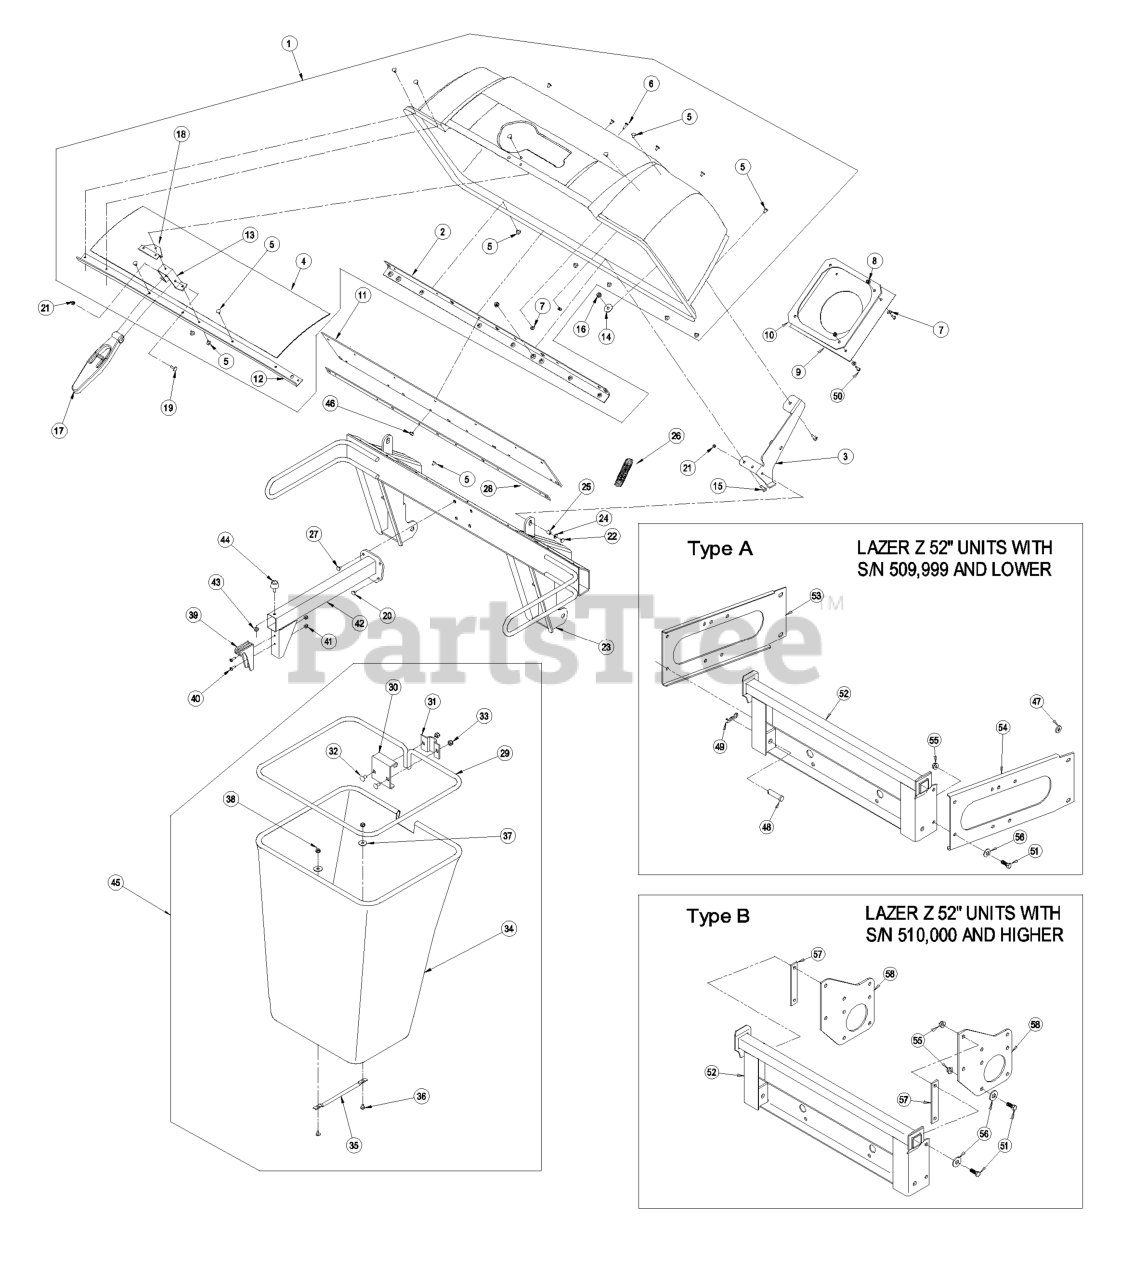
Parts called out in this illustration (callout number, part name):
1	ASM, HOOD
2	STIFFENER-BAGGER, TOP
4	SCREEN-BAGGER
5	RIVET-BLIND
6	SCREW-HEAD, TRUSS
7	WASHER-FLAT
8	NUT-LOCK, NI
9	SEAL-CHUTE
10	CLAMP-SEAL
11	SEAL-HOOD
12	SUPPORT-SCREEN
13	ANCHOR-LATCH
15	SCREW-HH
18	REINFORCEMENT-LATCH
19	SCREW-HH
20	SCREW-HSBH
21	NUT-LOCK, NI
22	SCREW-HH
23	UPRIGHT-BAGGER
24	WASHER-FLAT
26	SPRING-EXTENSION
27	SCREW-HH
28	PLATE-BACKING
29	FRAME-BAG
30	HANGER-BAG
32	BOLT-CARR
33	NUT-LOCK, NI
35	HANDLE-BAG
36	BOLT-CARR
38	NUT-LOCK, NI
40	SCREW-PPH
42	SUPPORT-BAG
46	NUT-LOCK, SIDE
47	SPACER
48	PIN-CLEVIS
49	PIN-COTTER
50	SCREW-PPH
51	SCREW-HH
52	MOUNT-BAGGER
53	BRACKET-FRAME, LH
54	BRACKET-FRAME, RH
55	NUT-HHF, WHIZ
56	WASHER-BELLEVILLE
57	SPACER
58	PLATE-MOUNT, BAGGER
